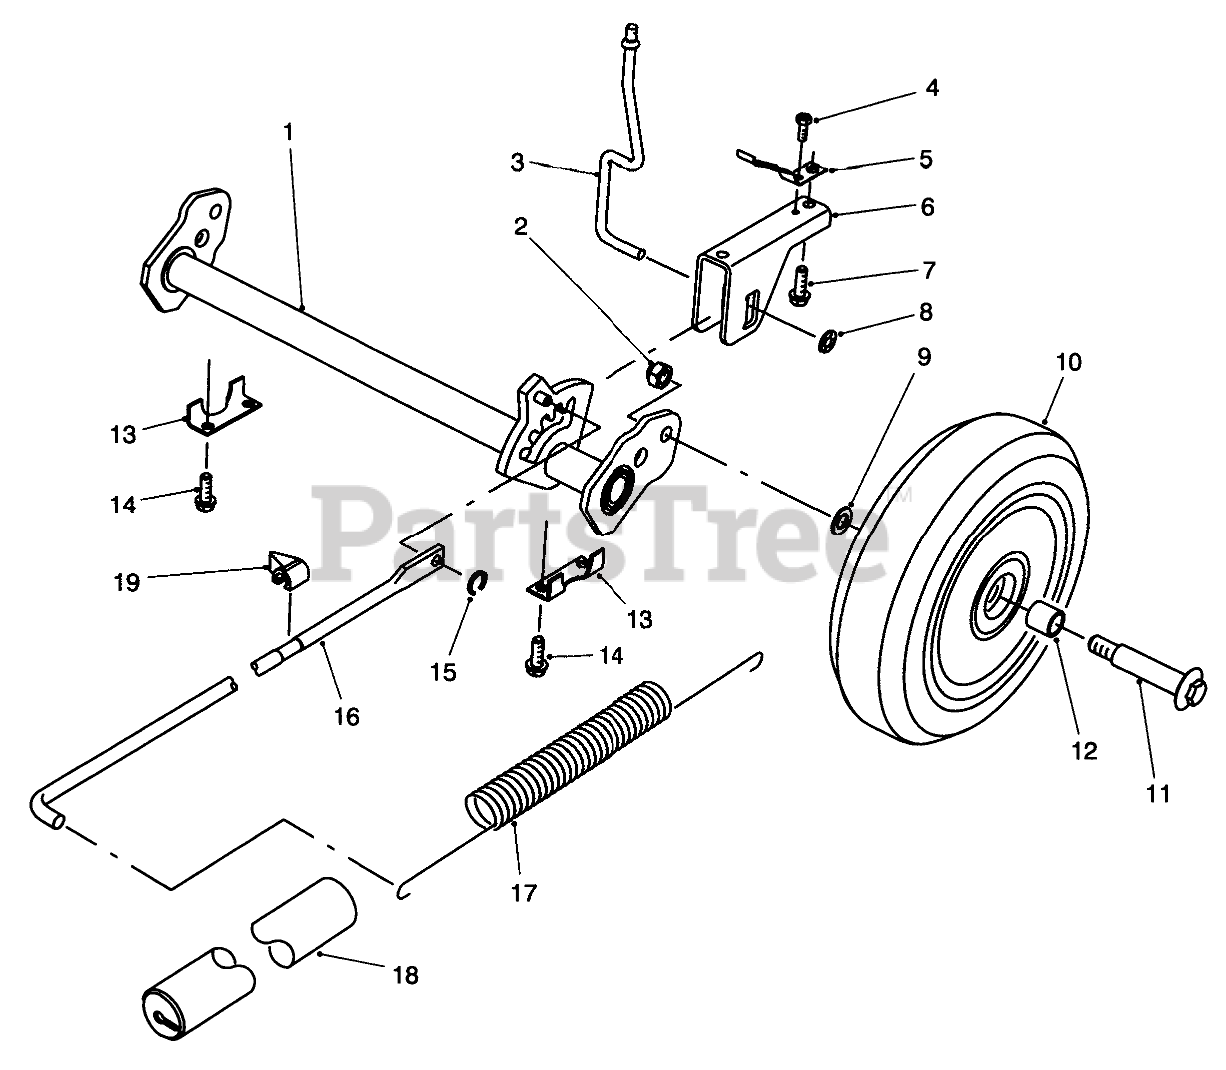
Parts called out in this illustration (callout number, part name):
1	PIVOT ARM REAR WA
2	NUT-HEX
3	TRIGGER ROD
4	SCREW 8 - 32 X 250
5	SPRING - TRIGGER RET
6	SADDLE - HOC
7	SCREW
8	PUSHNUT
9	WASHER
10	Wheel & Tire Assembly (Incl. Ref. #12)
11	BOLT-WHEEL
12	BUSHING
13	REAR SECURING PLATE
14	SCREW-HWH
15	GRIP RING
16	LINK ROD
17	SPRING-COUNTERBALANCE
18	COVER-SPRING
19	INDICATOR-HEIGHT OF CUT
